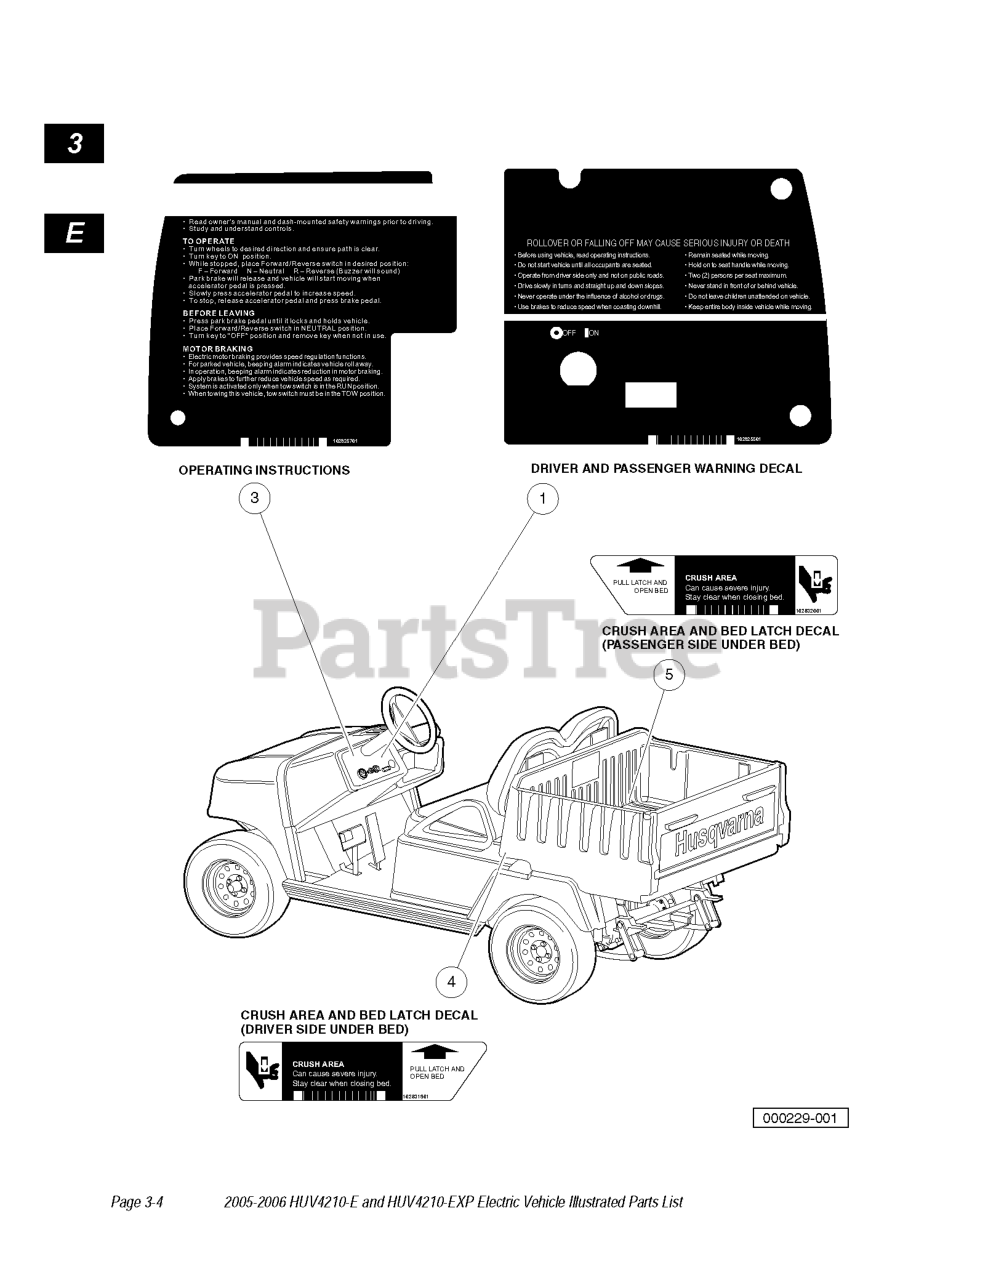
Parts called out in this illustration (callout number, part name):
1	DECAL, WARN, IP,E
3	DECAL, OPER INS
4	DECAL, WARN, BED LATCH LH
5	DECAL, WARN, BED LATCH RH
